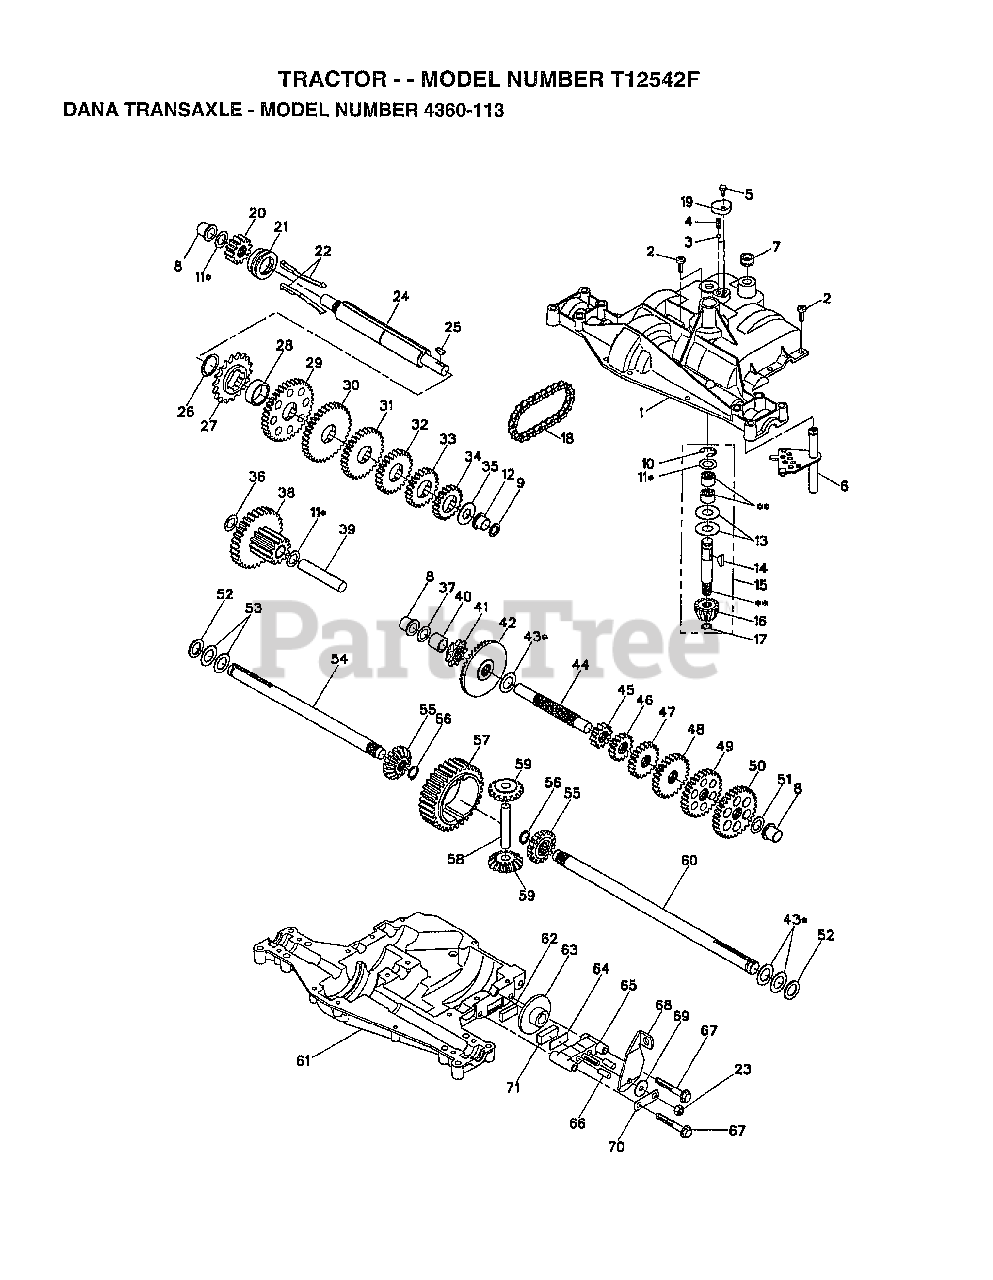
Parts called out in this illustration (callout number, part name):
1	HOUSING, UPPER
3	BALL, DETENT
4	SPRING, DETENT
5	SCREW, #10-24 X .482
6	SHIFTER ASSEMBLY
8	BEARING, FLANGE
10	RING, RETAINING
11	ASSY, KIT, SHIM .625 SHAFT
12	BEARING, FLANGE
13	WASHER, PLAIN .632 X 1.38 X .046
14	KEY, WOODRUFF, #9
15	ASSEMBLY, KIT, INPUT SHAFT
16	PINION, BEVEL, 14 TEETH
17	RING, RETAINING
18	CHAIN, 24 PITCHES
19	COVER, DETENT
20	GEAR, SPUR, 12T
21	COLLAR, CLUTCH
22	ASSEMBLY, KIT, CLUTCH KEYS
23	LOCKNUT 5/16-24
24	SHAFT, INTERMEDIATE
25	KEY, WOODRUFF, #61
26	RING, RETAINING
27	SPROCKET, 18 TEETH
29	GEAR, SPUR, 37 TEETH
30	GEAR, SPUR, 35T
31	GEAR, SPUR, 30 TEETH
32	GEAR, SPUR, 25 TEETH
33	GEAR, SPUR, 22 TEETH
34	GEAR, SPUR, 19 TEETH
35	WASHER, PLAIN .640 X 1.37 X .061
36	WASHER PLAIN
37	WASHER PLAIN
38	ASSY, GEAR COMB 12T & 30T
39	SHAFT, IDLER
40	SPACER .635 X .875 X .755
41	SPROCKET, 9 TEETH
42	GEAR, BEVEL, 42 TEETH
43	ASSY, KIT, SHIM .750 SHAFT
44	SHAFT, DRIVE
45	GEAR SPUR, 12 TEETH
46	GEAR, SPUR, 15T
47	GEAR, SPUR, 20 TEETH
48	GEAR, SPUR, 25 TEETH
49	GEAR, SPUR, 28 TEETH
50	GEAR, SPUR, 31 TEETH
51	WASHER, PLAIN .632 X 1.00 X .060
52	WASHER, NEOPRENE
53	WASHER, PLAIN .758 X 1.25 X .031
55	GEAR, MITER, 15 TEETH
56	RING, RETAINING
57	GEAR, SPUR, 32 TEETH
58	SHAFT, CROSS
59	GEAR, MITER, 15 TEETH
61	HOUSING, LOWER
62	PUCK, FRICTION
63	DISC, BRAKE
65	JAW, BRAKE
66	PIN, DOWEL
67	SCREW, 5/16-18 X 2.35
68	LEVER ACTUATING
69	WASHER, PLAIN .321 X 1.00 X .055
70	BRACKET, ANTI-ROTATION
71	PUCK, FRICTION
